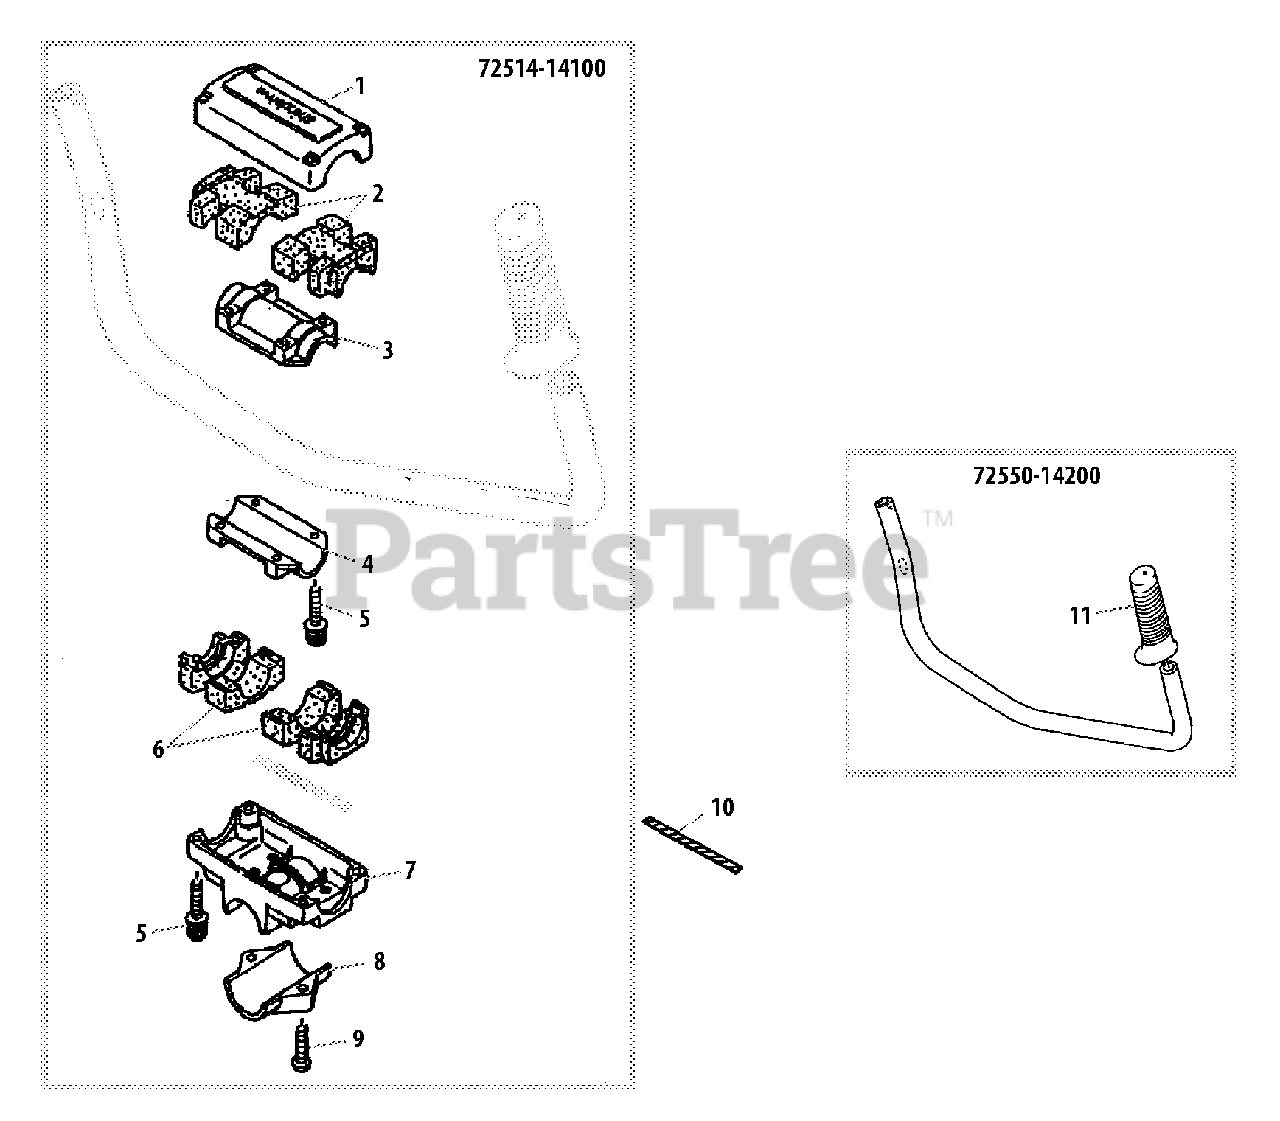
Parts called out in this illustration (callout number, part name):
1	CAP - UPPER
2	CUSHION - UPPER
3	CLAMP - UPPER
4	CLAMP - LOWER
5	SCREW - 5X25
6	CUSHION - LOWER
7	BRACKET, HANDLE
8	SPACER
9	SCREW - 6X25
10	LEAD - GROUND
11	GRIP
72514-14100	HANDLE BRACKET KIT
72550-14200	HANDLE ASSY
